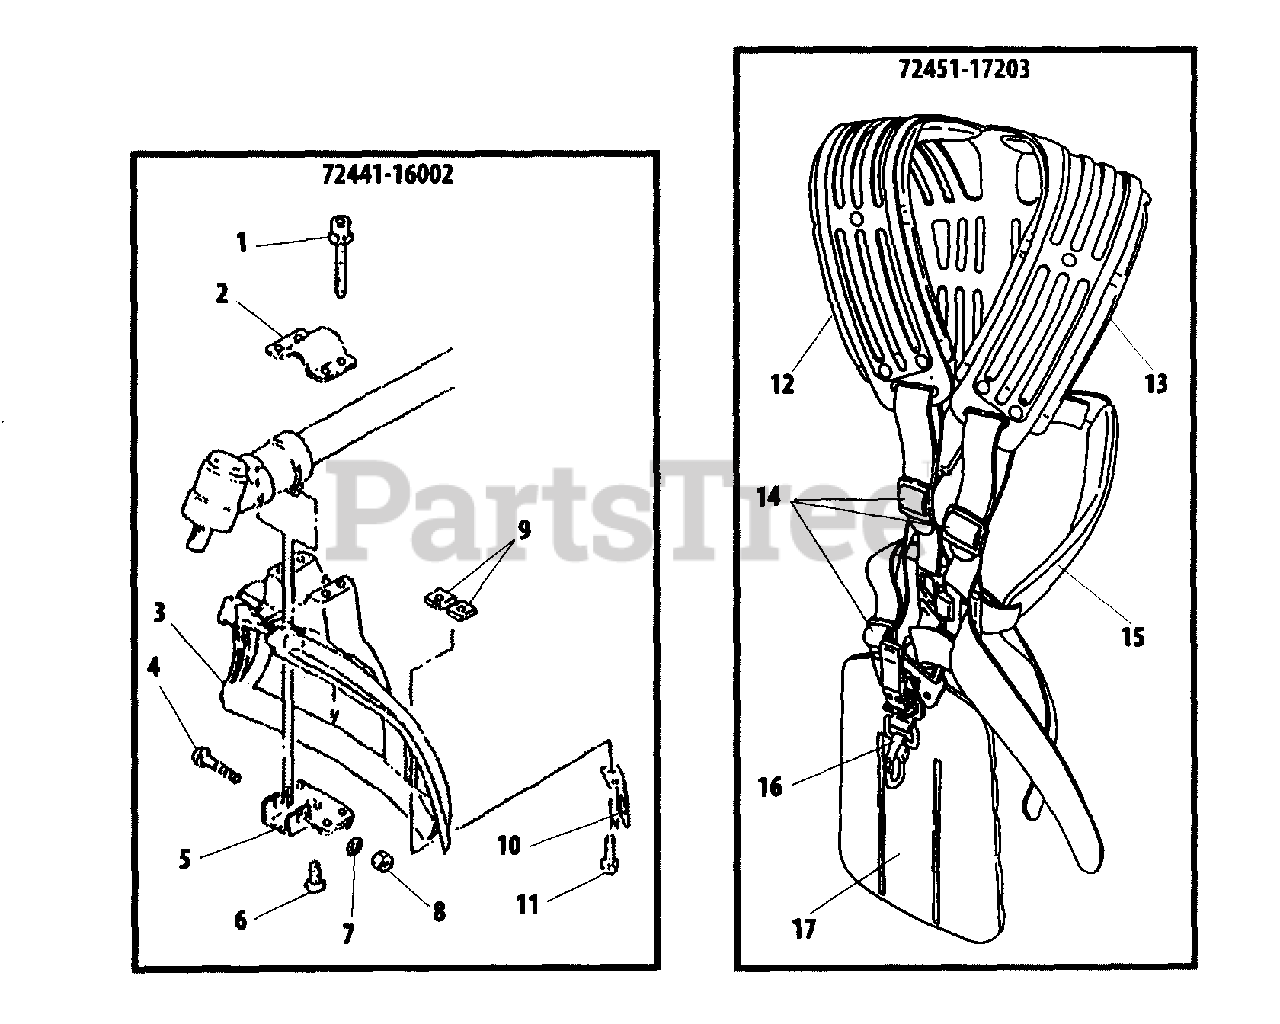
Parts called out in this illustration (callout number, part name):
1	SCREW - 5X45
2	CLAMP - UPPER
3	SHIELD, DEBRIS
4	SCREW - 6X40
5	CLAMP - LOWER
6	SCREW
7	WASHER - 6
8	NUT - 6
9	NUT - 5
10	KNIFE, TRIMMER LINE
11	SCREW - 5X16
12	PAD, SHOULDER - RIGHT
13	PAD, SHOULDER - LEFT
14	BUCKLE
15	PAD
16	HOOK
17	PAD
72441-16002	DEBRIS SHIELD KIT
72451-17203	HARNESS ASSY
